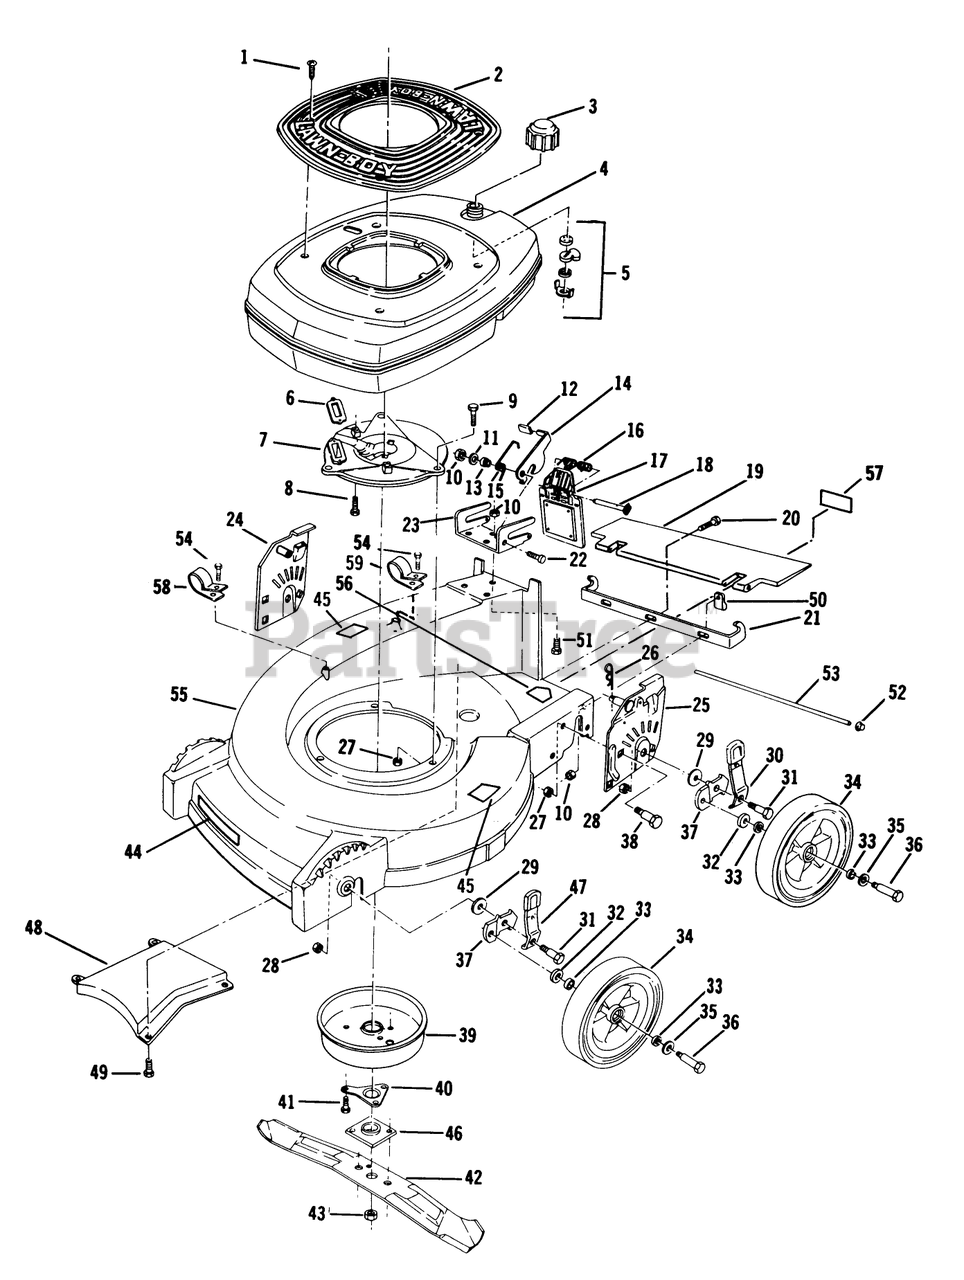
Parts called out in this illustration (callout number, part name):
1	SCREW - SELF TAPPING
3	FUEL CAP & INSERT
5	SHUT-OFF VALVE S
7	PLATE F
8	SCREW V
9	SCREW-HH
10	LOCKNUT E
15	SPRING
16	SPRING ASOC
18	ROD (RB&W)
19	T/SHIELD SM&P
26	HAIR PIN
27	NUT-LOCK F
28	LOCKNUT
29	WASHER
30	Knob and Spring Assembly
31	BOLT
32	WASHER WROUGHT
33	WASHER
35	SPACER
36	BOLT WHEEL
39	MUFFLER COVER F
40	SUPPORT F
41	SCREW
43	NUT-BLADE
46	PLATE AND COLLAR ASM
48	BAFFLE CHUTE PL
54	SCREW LAWRENCE
